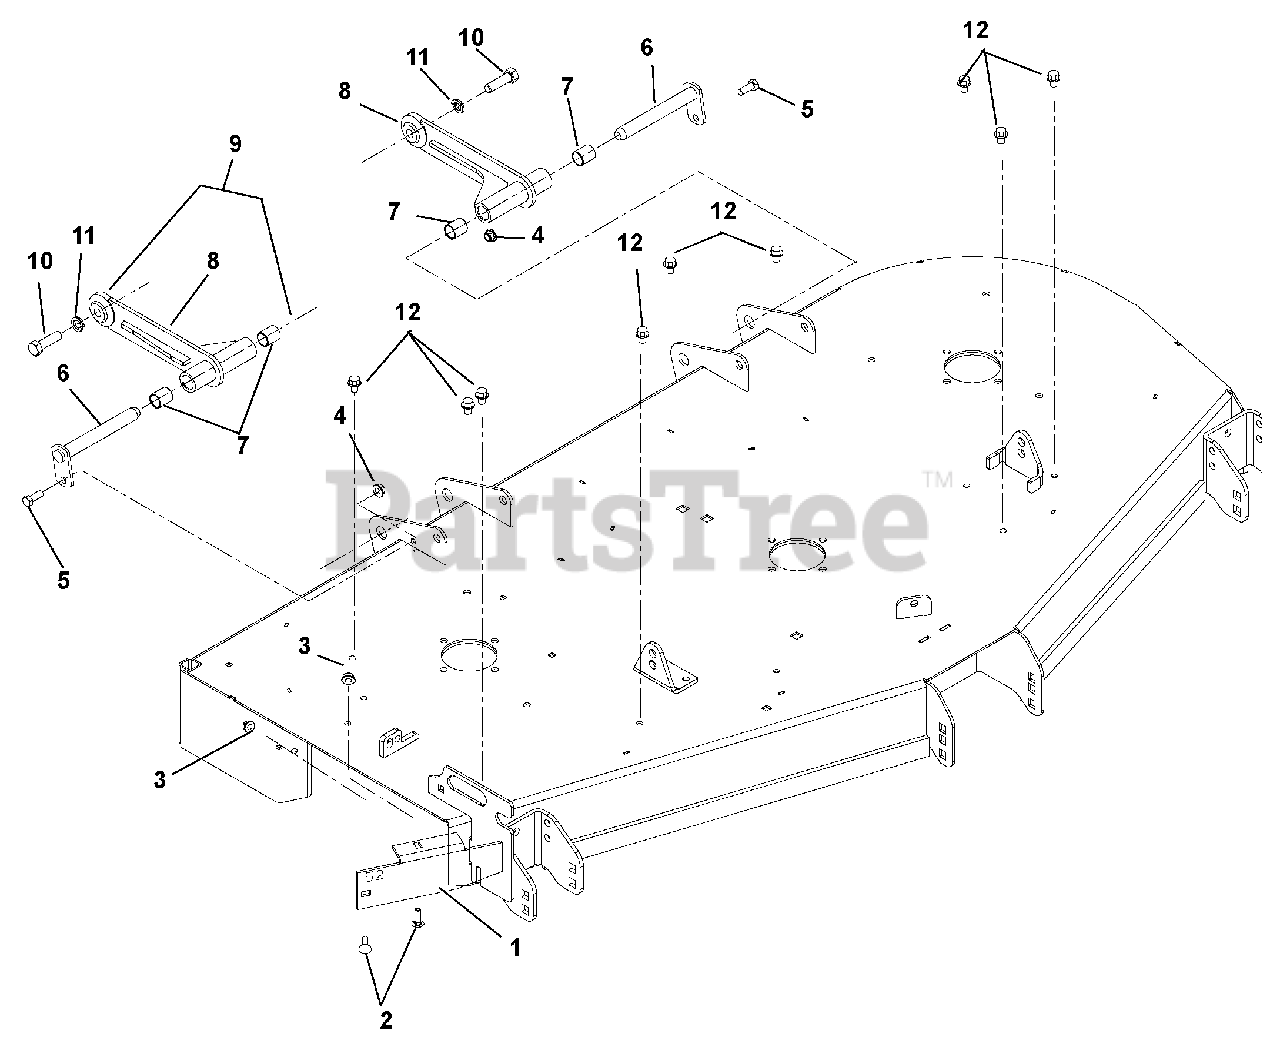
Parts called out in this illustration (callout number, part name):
1	Discharge Baffle, 44" & 48" (991082, 090)
1	Discharge Baffle, 60" (991084, 091)
1	Discharge Baffle, 52" (991083)
2	Bolt, Round Head Square Neck .31-18 x 1.00 Grade 5
3	Nut, .31-18 Nyloc Flange
4	Nut, .38-16 Nyloc Flange
5	Bolt, Hex .38-16 x 1.00 Grade 5
6	Weldment, Mower Mounting Pin
7	Bearing, .75 x .875 x 1.00
8	Deck Pusher Arm Weldment
9	Assembly, Mower Mount Arm (Includes items 7 and 8)
10	Bolt, Hex .50-13 x 1.75 Grade 5 EP80
11	Washer, Locking .50 x .125 Regular
12	Screw, Tapping .38-16 x .50 Hex Washer Head
